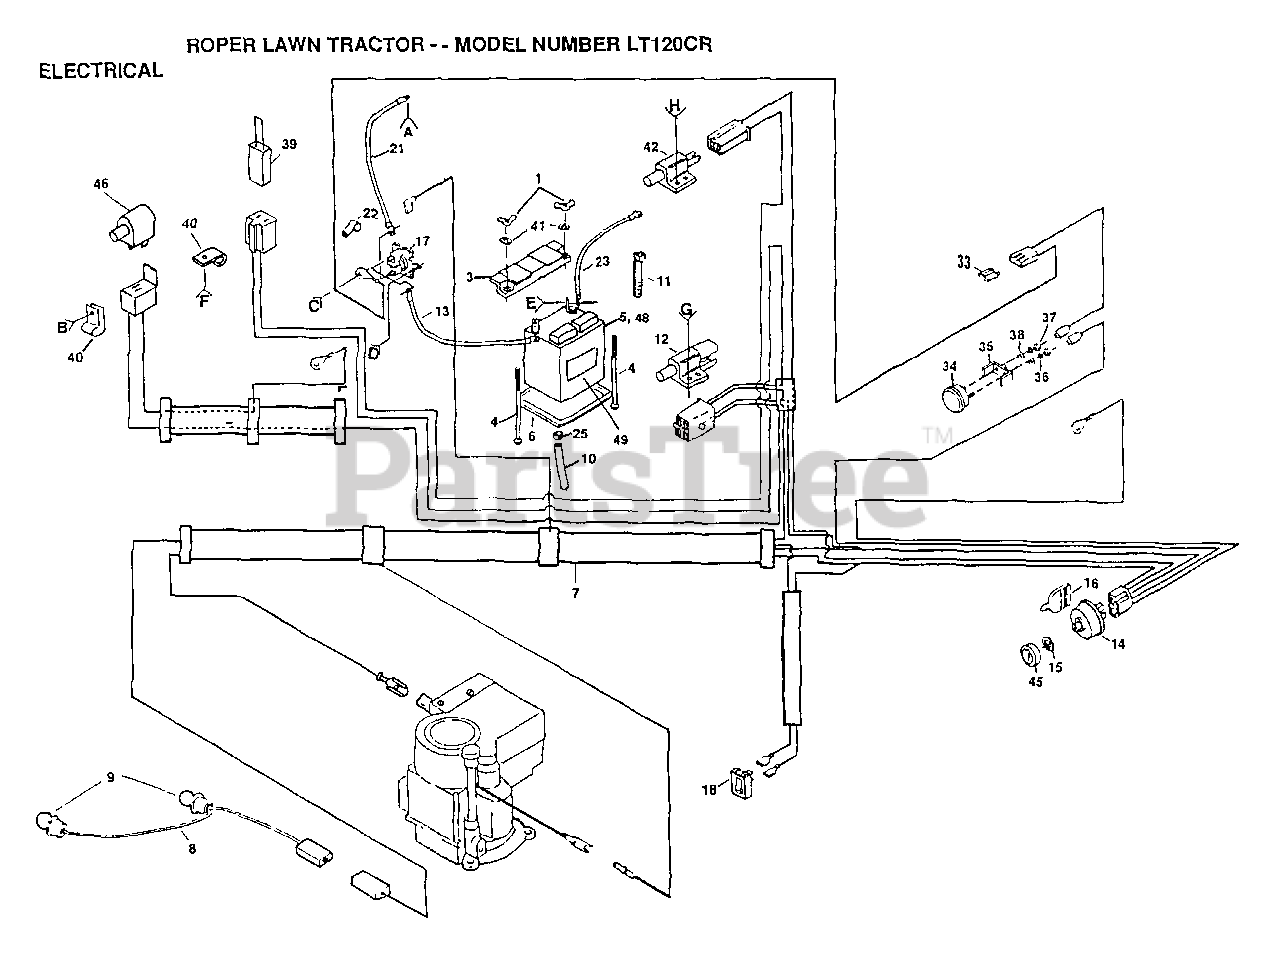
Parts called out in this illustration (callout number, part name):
4	BOLT
6	"TRAY T, BATTERY"
8	HARNESS T
11	WIRE TIE
12	SWITCH INTERLOCKT
13	CABLE-BATTERY T
18	SWITCH LT
21	"CABLE T, BATTERY"
23	CABLE T
25	HOSE CLAMP T
33	FUSE HYT
34	AMMETER T
38	WASHER
40	CLIPT
41	LOCKWASHER GT
42	SWITCH-INTER. GT
46	SWITCH SEAT
48	"CAP,BATTERY "
49	DECAL
